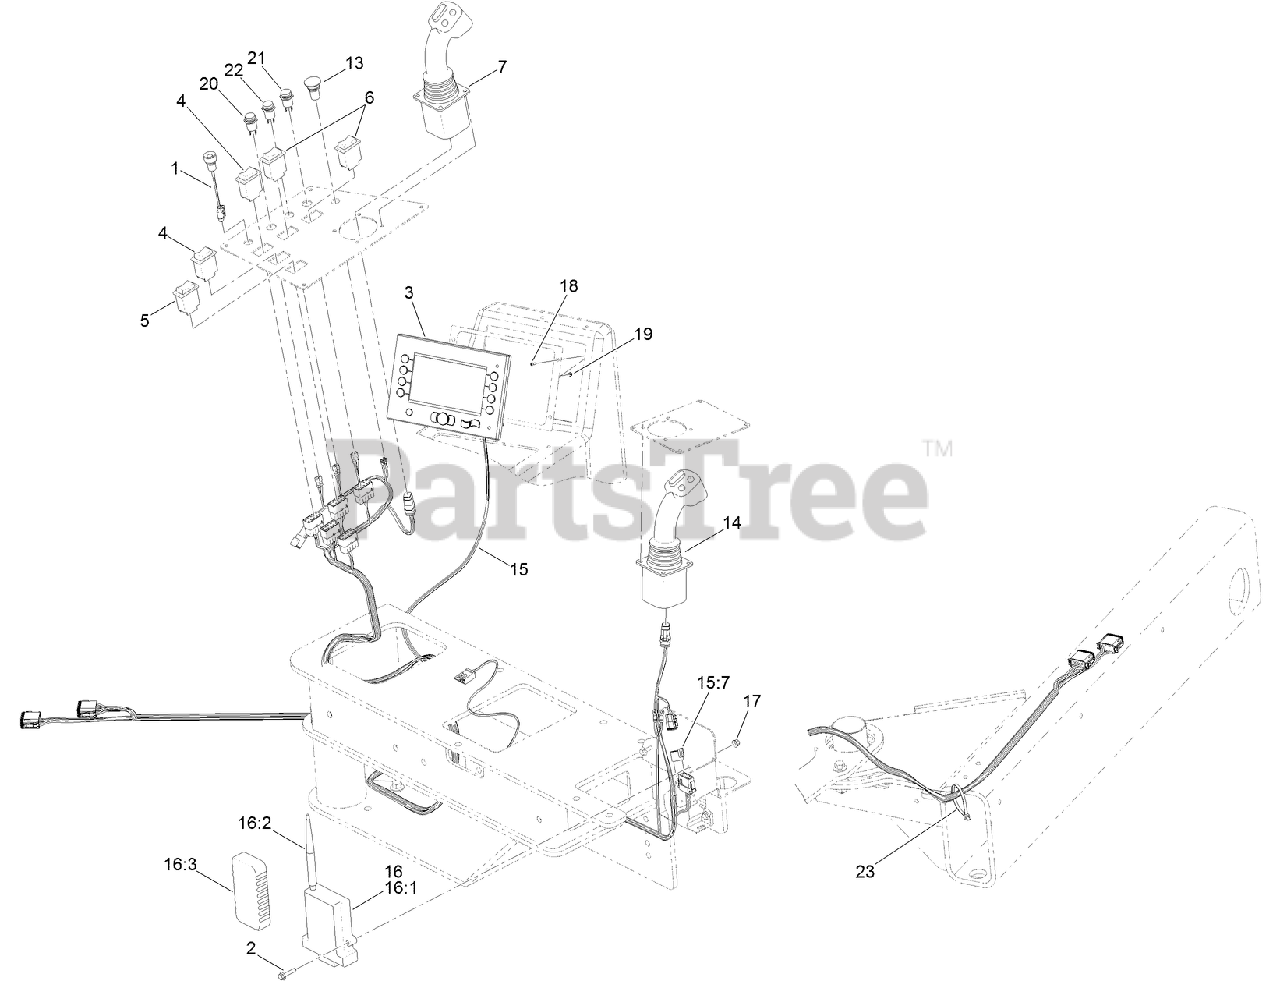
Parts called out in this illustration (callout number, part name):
1	SWITCH-START, GREEN BUTTON
2	SCREW-HHF
3	DISPLAY-DP610TM, UNPROGRAMMED
4	SWITCH-ROCKER, 2 POLE (ON/OFF)
5	SWITCH-ROCKER, 2 POLE
6	SWITCH-ROCKER, 1 POLE (ON)OFF/ON(OFF)
7	JOYSTICK-MODIFIED (LEFT HAND)
13	BUTTON-PUSH, RED MUSHROOM
14	JOYSTICK-CARRIAGE
15	HARNESS-WIRE, OPERATOR
15:7	RESISTOR-120 OHM
16	LONG RANGE EXIT SIDE LOCKOUT KIT
16:1	HANDHELD-RANGE, LONG
16:2	BASE UNIT-RANGE, LONG
16:3	ANTENNA-LOCKOUT
17	NUT-FLANGE, NI
18	SCREW-PH
19	NUT-LOCK, NI
20	LAMP-INDICATOR, LED
21	LAMP-INDICATOR, LED
22	LAMP-INDICATOR, LED
23	TIE-CABLE
